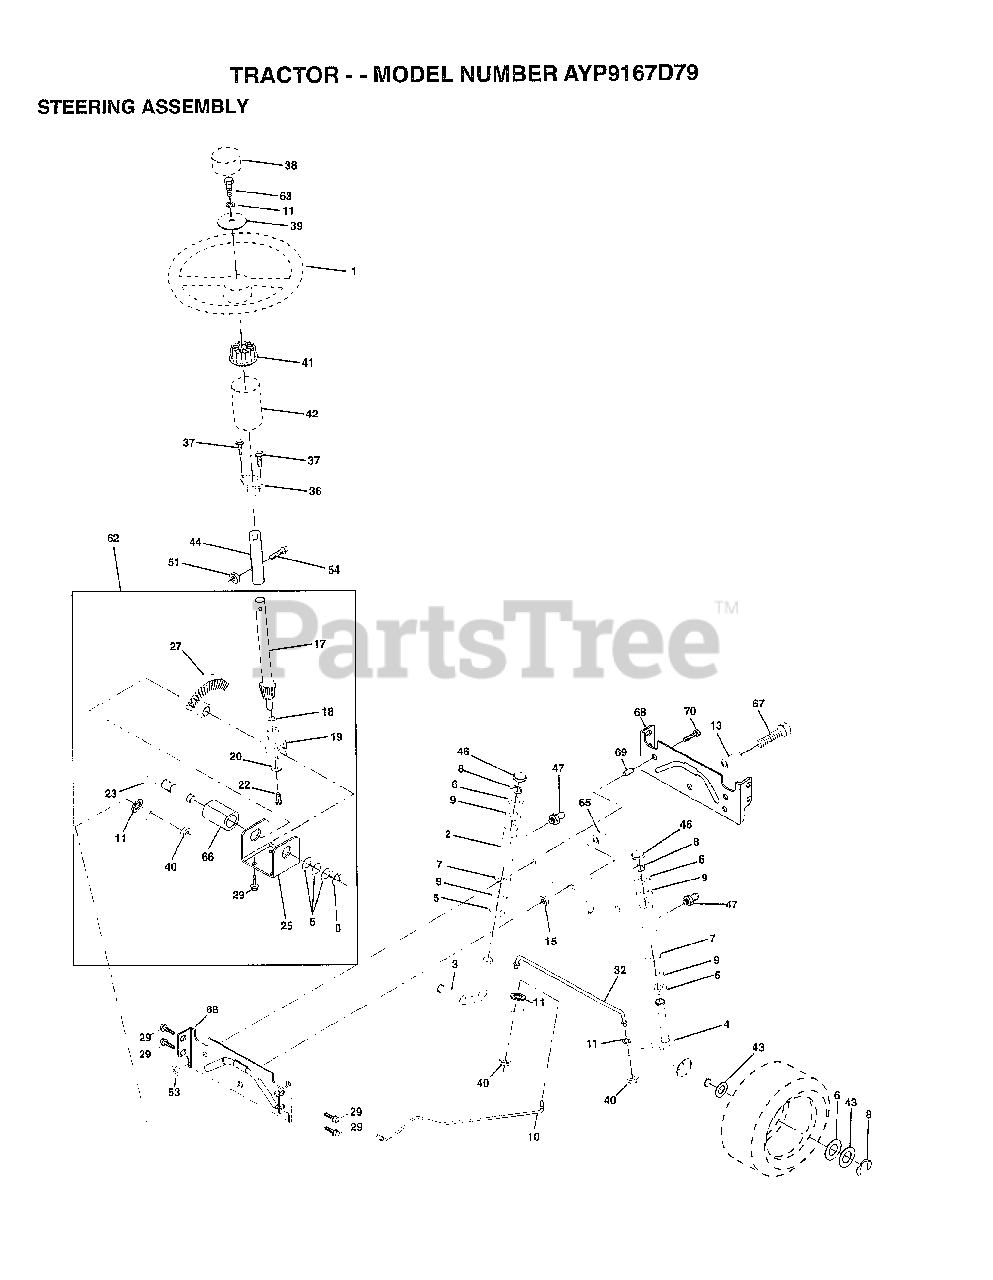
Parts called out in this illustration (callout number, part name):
1	WHEEL STR AYP BLK
3	"SPINDLE ASM,LH"
4	"SPINDLE ASM,RH"
5	WASHER .T
6	WASHER
7	WASHER
8	RING
9	COL. SRTG. BEAR.
10	LINK.DRAG
11	LOCKWASHER
13	BEARING AXLE
15	"NUT-LOC,FLANGE LT"
17	SHAFT ASM STEERIN
18	THRUST WASHER
19	SUPPORT.SHAFT
22	SCREW HEX SOC1/4-
25	BRKT-STEERING
27	GEAR SECTOR
29	SCREW
32	ROD.ASM.TIE.BALL
36	BUSHING.STEERING
37	"SCREW-TT,10-32 FL"
38	CAP STEER AYP
39	WASHER T
40	GRIPCO NUT
41	ADAPTER LT
42	BOOT.STEER.PL
43	WASHER
44	EXT SHAFT STEERIN
46	CAP
47	ZERK M
51	NUT
54	BOLT
62	KIT STEERING ASM
63	BOLT
65	SPACER AXLE
66	"BEARING-ARM,PITMA"
67	BOLT
68	BRACE AXLE
69	"SPACER BRCAE,AXLE"
70	BOLT.HEX.3/8-16X2
